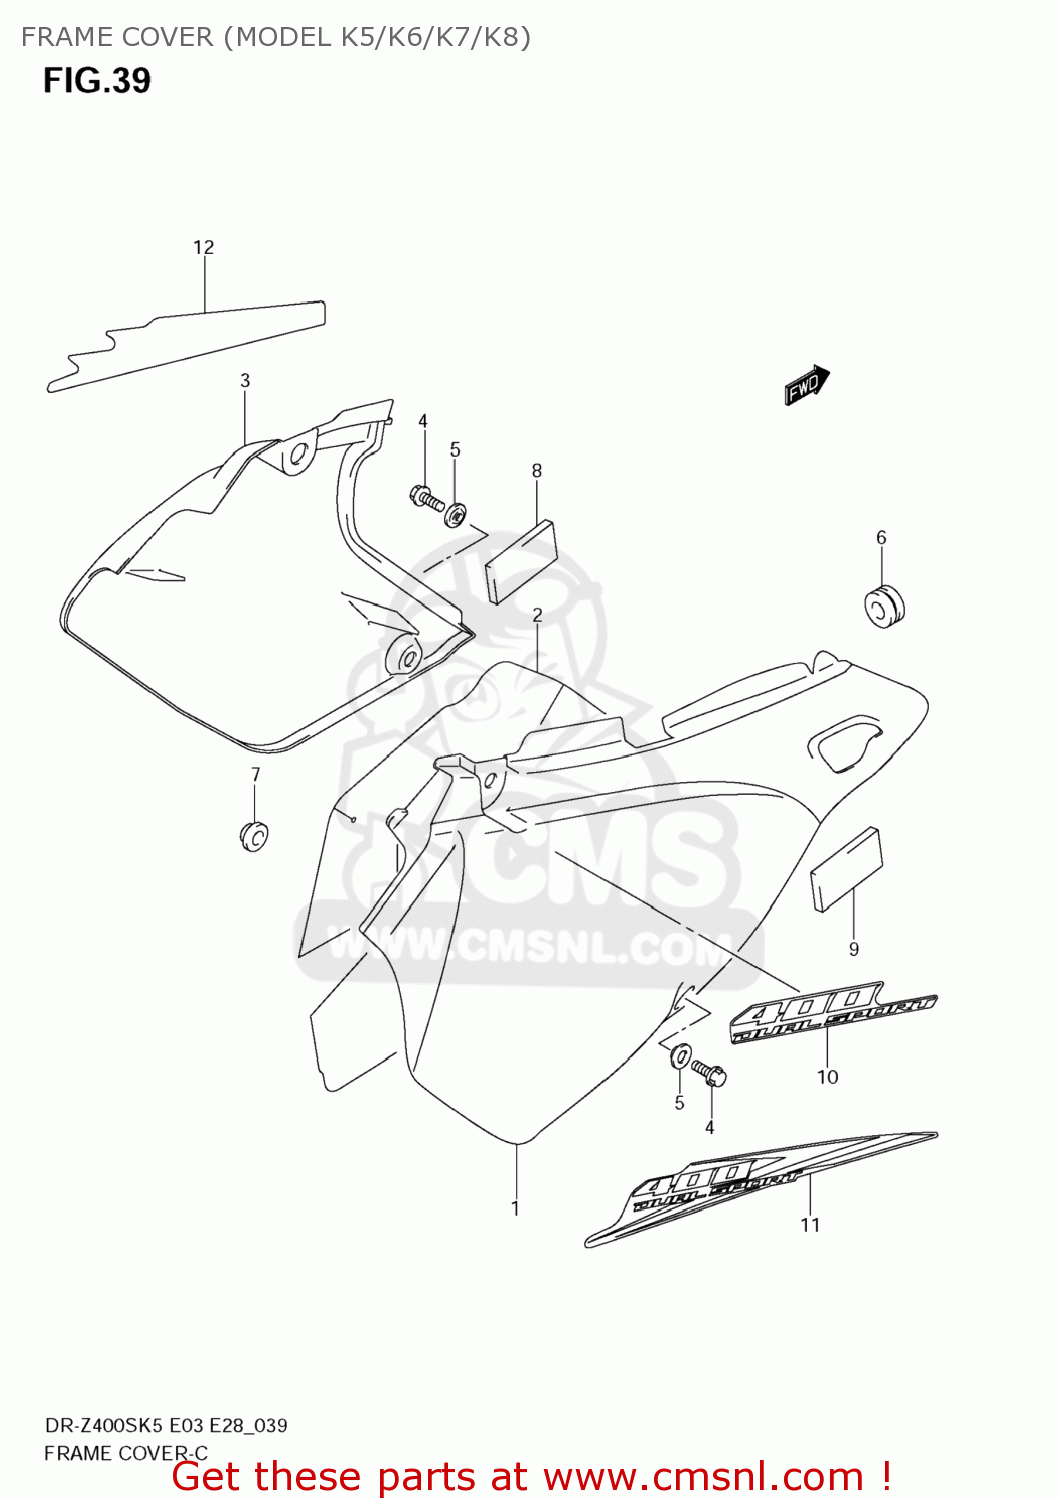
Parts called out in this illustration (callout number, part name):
1	COVER,FRAME,R(WHITE)
2	SHIELD,FRAME COVER,R
3	COVER,FRAME,L(WHITE)
4	BOLT
5	WASHER
6	CUSHION
7	CUSHION
8	CUSHION,FRAME COVER,L
9	CUSHION
10	EMBLEM,FRAME COVER
11	TAPE,FRAME COVER,R
12	TAPE,FRAME COVER,L
